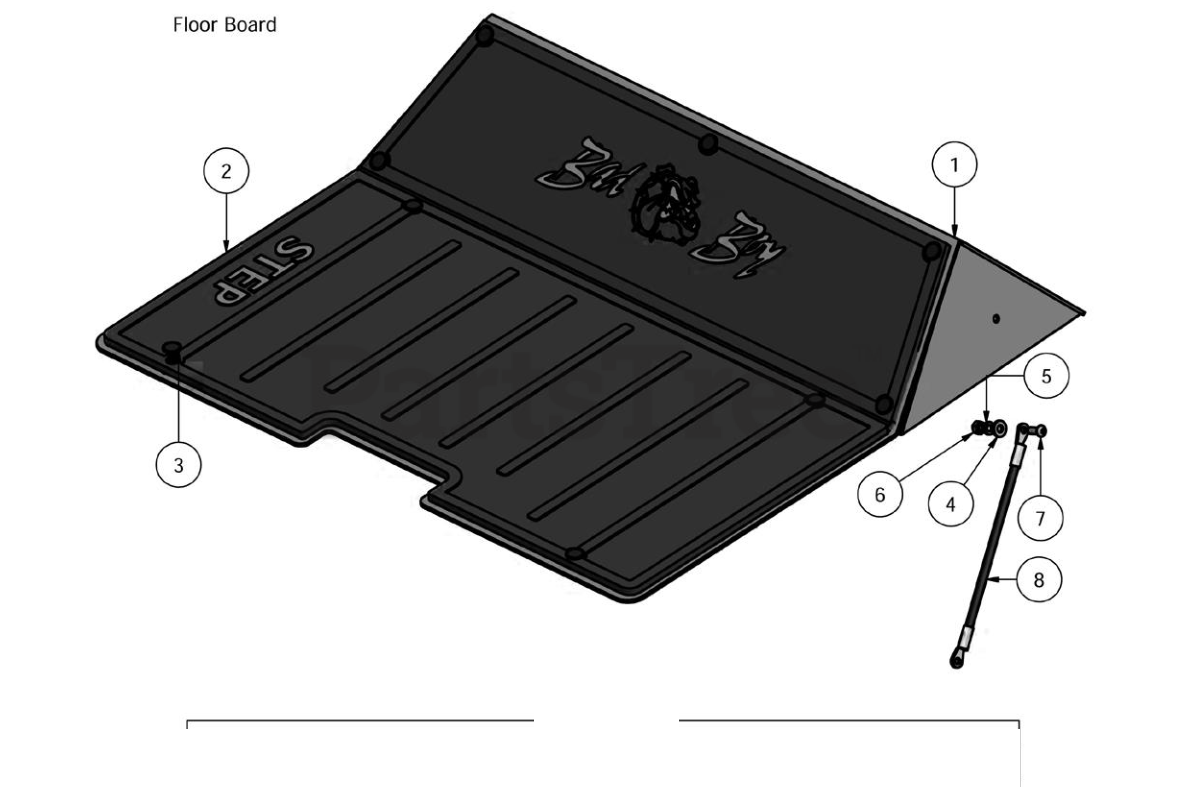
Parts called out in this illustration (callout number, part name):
1	Floor Panel
3	Ratchet Fastener
4	1/4" Flat Washer
5	1/4" Lock Washer
6	1/4" Hex Nut
7	1/4" x 5/8" Buttonhead Bolt
8	Floor Panel Cable
